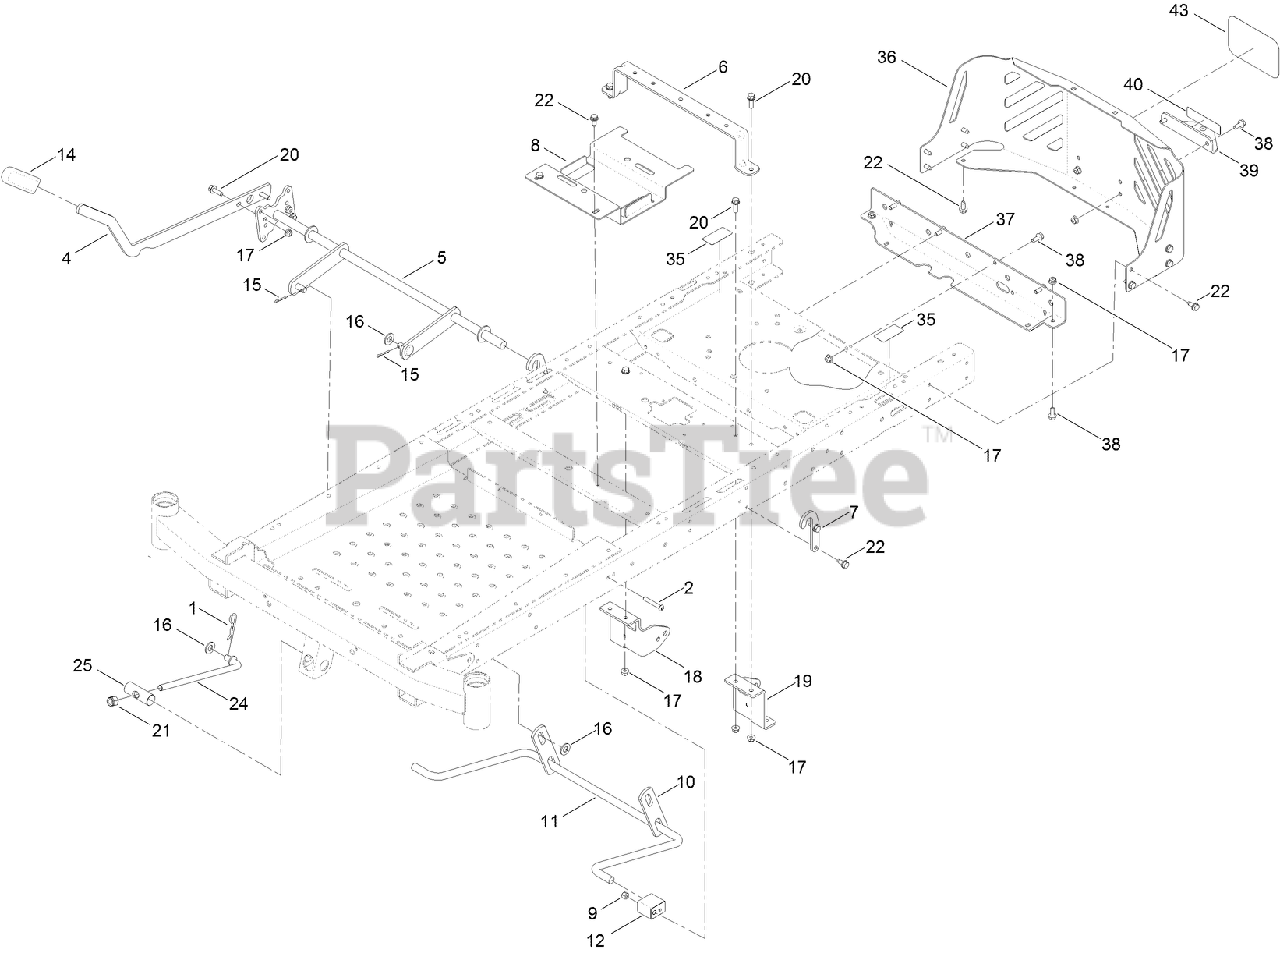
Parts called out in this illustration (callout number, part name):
1	PIN-COTTER
2	SCREW-HSBH
4	LEVER-LIFT
5	LIFT-DECK, WIDE
6	BRACE-SEAT, REAR
7	BRACKET-LIFT
8	BRACKET-BATTERY
9	NUT-LOCK, NI
10	LINK-LIFT
11	ARM-LIFT, REAR (WIDE)
12	BLOCK-PIVOT
14	GRIP-LEVER
15	PIN-COTTER
16	WASHER-FLAT
17	NUT-HF, NI
18	MOUNT-HYDRO, FRONT (RH)
19	MOUNT-HYDRO, FRONT (LH)
20	SCREW-HHF
21	NUT-HEX
22	SCREW-HWHTF
24	ROD-MOUNT, DECK
25	PIN-PIVOT
35	DECAL-BYPASS
36	GUARD-ENGINE, WIDE
37	CROSSMEMBER-REAR, WIDE
38	SCREW-HHF
39	BRACKET-HITCH
43	DECAL
